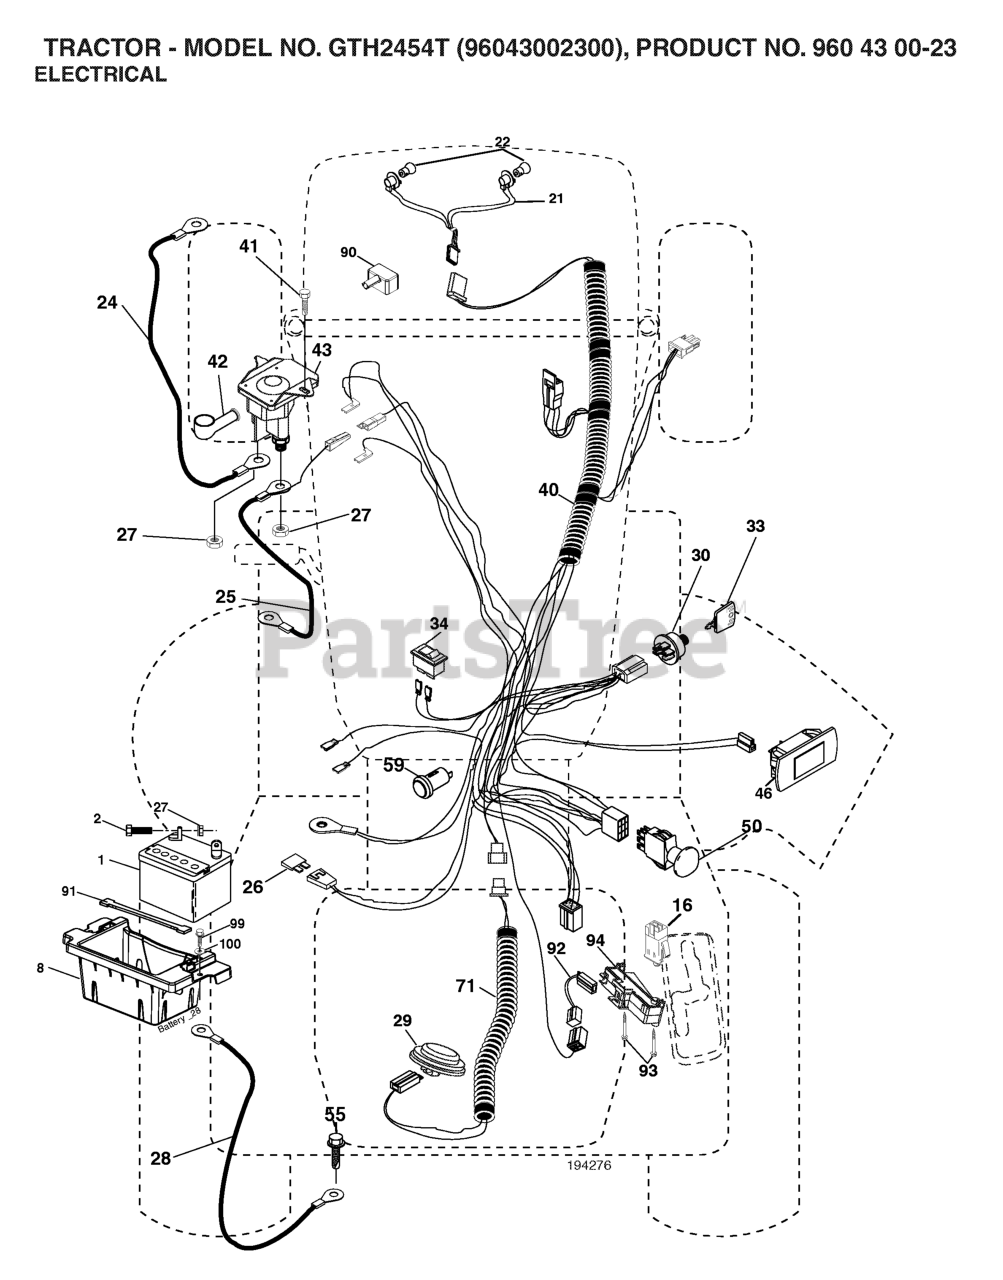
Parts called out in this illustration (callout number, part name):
1	BATTERY 12V .35 AMP
2	BOLT.HEX.1/4.X.3/4.DICHROMATE
8	BOX.BATTERY.MOUNT.FRONT.LT
16	SWITCH INTERLOOK PUSH-IN
21	HARNESS ASSY LIGHT
24	CABLE.BATT.POS.WIRE.TG.DA SOL
25	CABLE.START.RED.17.5".
26	FUSE 20AMP
27	NUT
28	CABLE GROUND 6 GA 21" 90T BLK
29	SWITCH.SEAT.DELTA.OPC.
30	SWITCH.IGN.DELTA.W.LGH.ROS
33	KEY MLD GEN DELTA
40	HARNESS-CHASSIS SUB
41	SCREW THD CUT .25X20X.5
42	TERMINAL COVER
43	SOLENOID.W/BRASS.PLUNGER
46	GAUGE.SERVICEMINDER.HR
50	RP.PTO.SWITCH.8 TERMINAL.BLACK
55	SCREW.THDROL.5/16-18X3/4.TTY
59	OUTLET.12-VOLT
71	HARNESS.IGN.DASH.HUQ/PRED.OUTL
90	COVER TERMINAL
91	STRAP.BATTERY.MOUNT.FRONT(2 2)
92	HARNESS.PIGTAIL.CONSLE
93	SCREW.PLASTITE
94	MODULE.REVERSE.ROS
99	SCREW HEXWSHR 1/4-20X3/4
